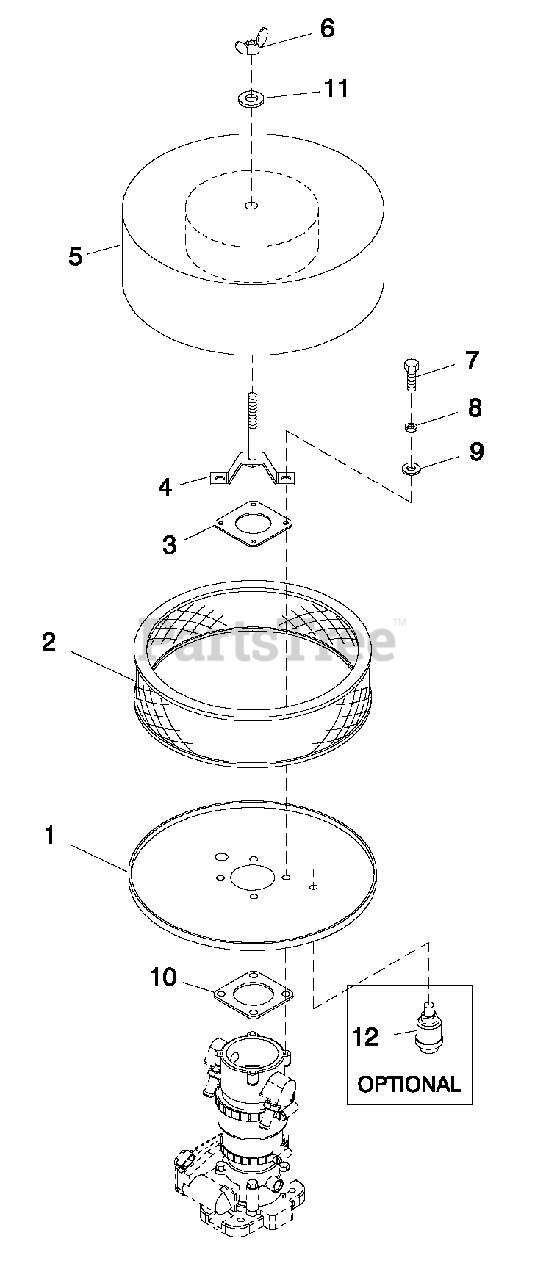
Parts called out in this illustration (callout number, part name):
1	AIR CLNR BTM PLT W/CPLR 8.1L
2	ELEMENT AIR FILTER
3	TOP PLATE VENTURI
4	HOLD DOWN AIR CLEANER PLATED
5	PLATE AIR CLEAN TOP 5.4L/6.8L
6	NUT WING 1/4-20 NYLK
7	SCREW HHC M6-1.0X 16 G 8.8
8	WASHER LOCK M6-1/4
9	WASHER FLAT M6
10	GASKET MIXER BODY
11	WASHER FLAT 1/4-M6 ZINC
12	INDICATOR FILTER MINDER
